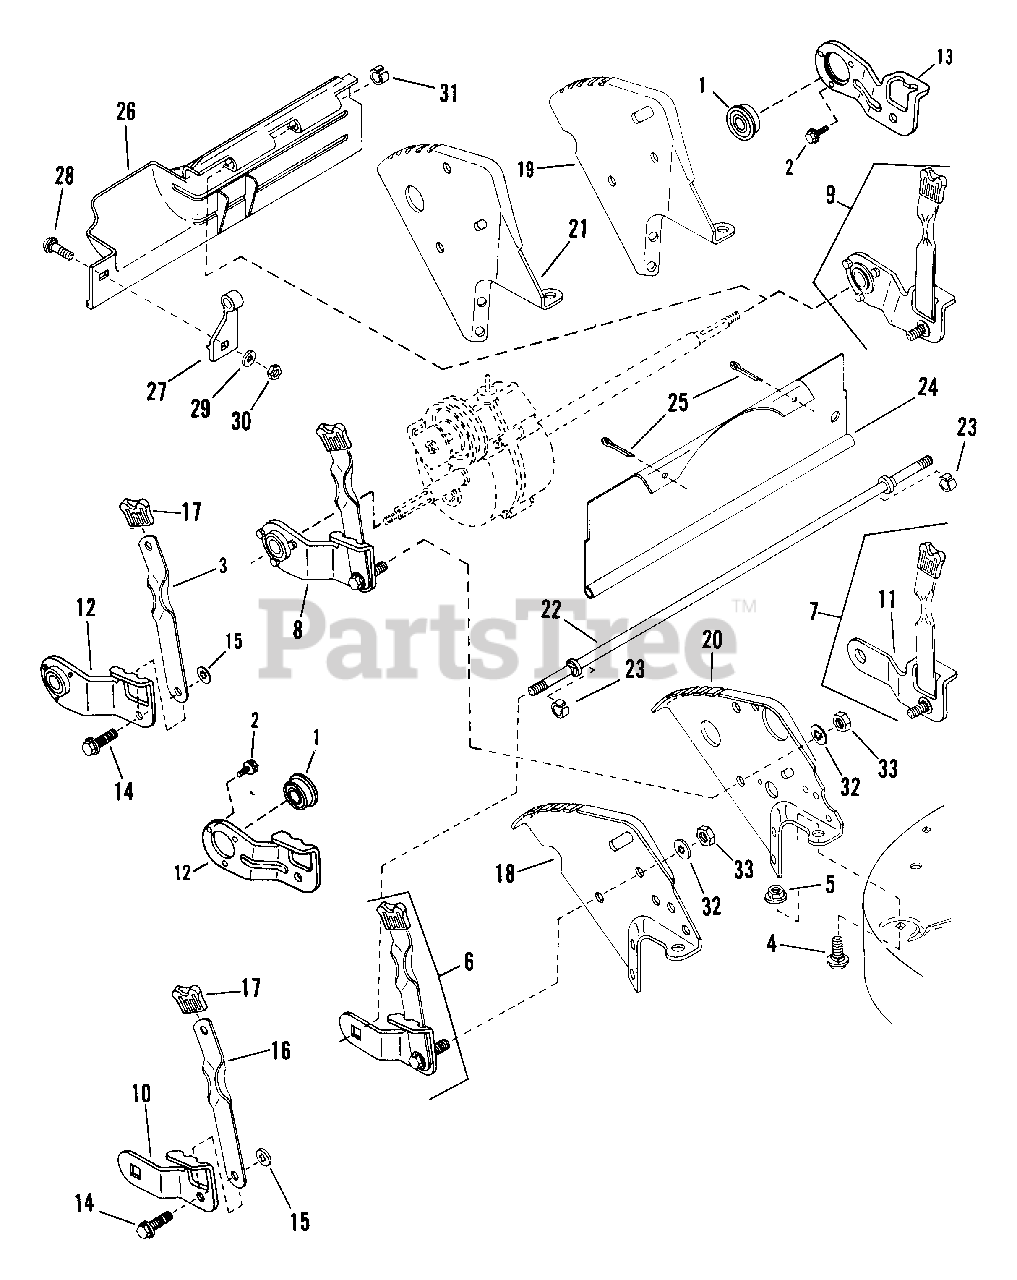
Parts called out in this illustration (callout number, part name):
1	BEARING
2	SCREW, #10-32 x 3/8" Self-Tapping
3	LATCH, Height Adjusting
4	BOLT, 5/16-18 x 1/2" Short Neck Carriage
5	NUT, 5/16-18 Hex Flange Lock
6	ASSEMBLY, Wheel Arm (Square Hole, Front Left & Rear Right)
7	ASSEMBLY, Wheel Arm (Round Hole, Front Right & Rear Left)
8	WHEEL ARM ASSEMBLY (Rear Right "P" Models)
9	WHEEL ARM ASSEMBLY (Rear Left "P" Models)
10	ARM (Square Axle End)
11	ARM (Round Axle End)
12	ARM, Wheel Rear Right "P" Models
13	ARM, Wheel Rear Left "P" Models
14	BOLT, 5/16-18 x 1 Shoulder
15	RETAINER, 5/16 Bolt
16	LATCH, Height Adjusting
17	GRIP, Latch
18	BRACKET, Right Rear Wheel
19	BRACKET, Left Rear Wheel
20	BRACKET, Right Rear Wheel
21	BRACKET, Left Rear Wheel
22	AXLE
23	RING
24	GUARD, Rear Foot
25	PIN, 1/8 x 1-1/2" Cotter
26	GUARD, Rear Foot
27	SUPPORT, Foot Guard
28	BOLT, 1/4-20 x 1/2 Short Neck Carriage Gr.5
29	WASHER, 1/4 Int. Tooth Lock
30	NUT, 1/4-20 Hex
31	RING
32	WASHER, 5/16 Int. Tooth Lock
33	NUT, 5/16-18 Hex
